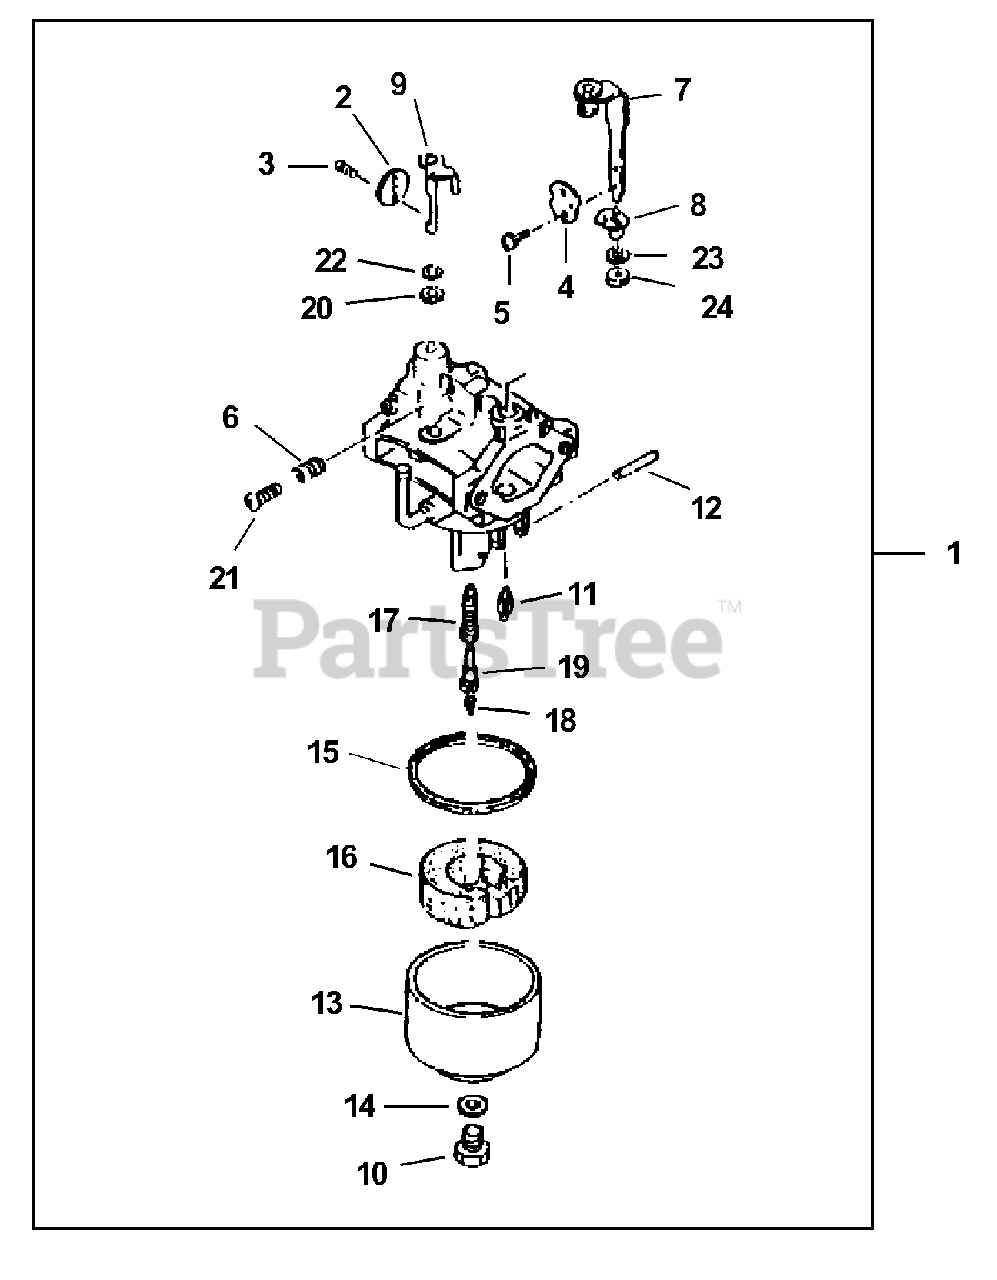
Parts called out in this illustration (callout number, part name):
1	Carburetor
2	Throttle valve
3	Screw (M3 X 0.5 X 4L)
4	Choke valve
5	Screw (M2.5 X 0.45 X 4L)
7	Choke lever
9	Throttle shaft
10	Bolt (M8 X 1.25 X 7L)
11	Needle valve
12	Float pin
13	Float chamber body
15	Chamber packing
17	Main nozzle
18	Main jet
21	Screw-Mixture
23	Choke cap
